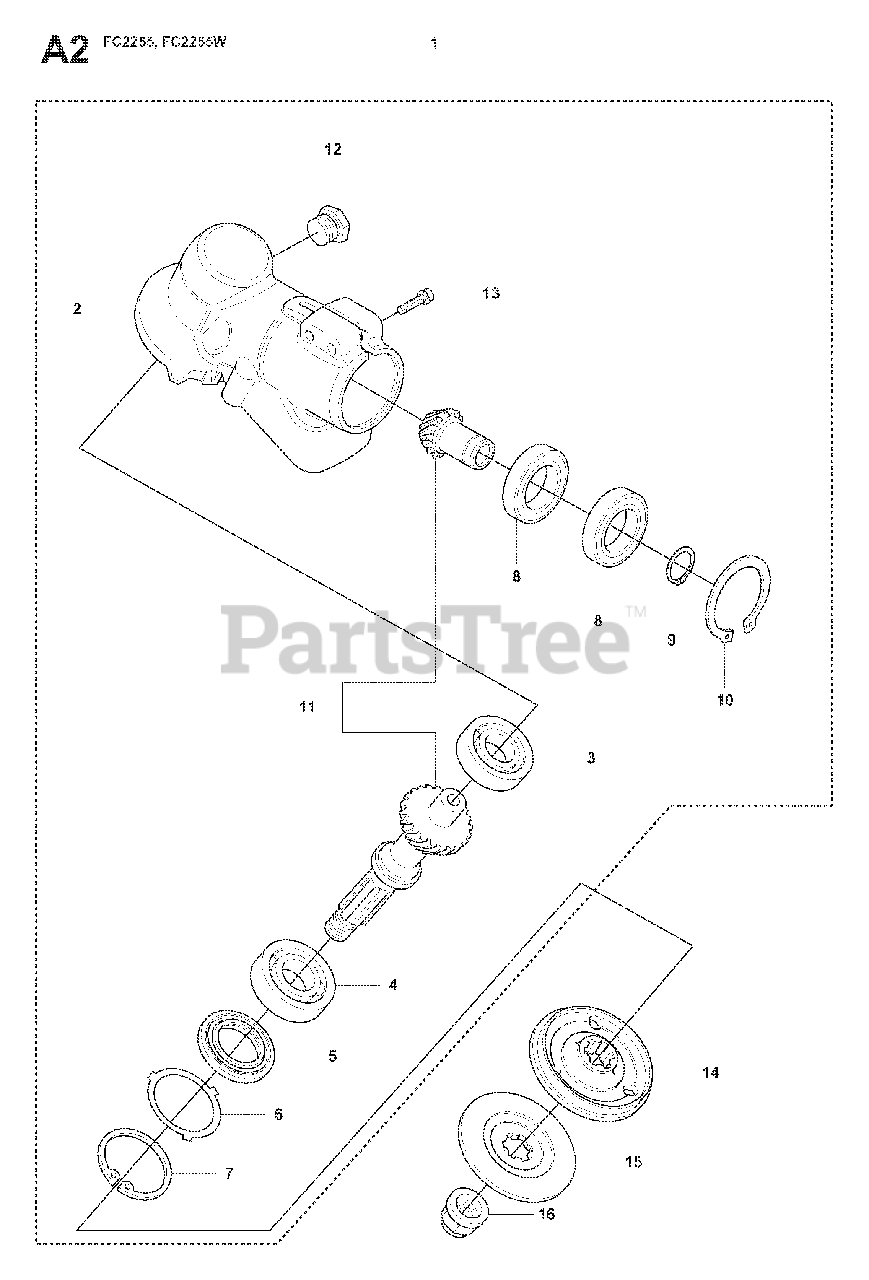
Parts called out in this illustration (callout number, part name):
1	RP BEVEL GEAR
2	%GEAR HOUSING
3	BALL BEARING
4	BALL BEARING
7	RETAINING RING SGH 35
8	BALL BEARING
9	RETAINING RING SGA 15
10	RETAINING RING
11	BEVEL GEAR
15	SUPPORT FLANGE
16	BLADE NUT
